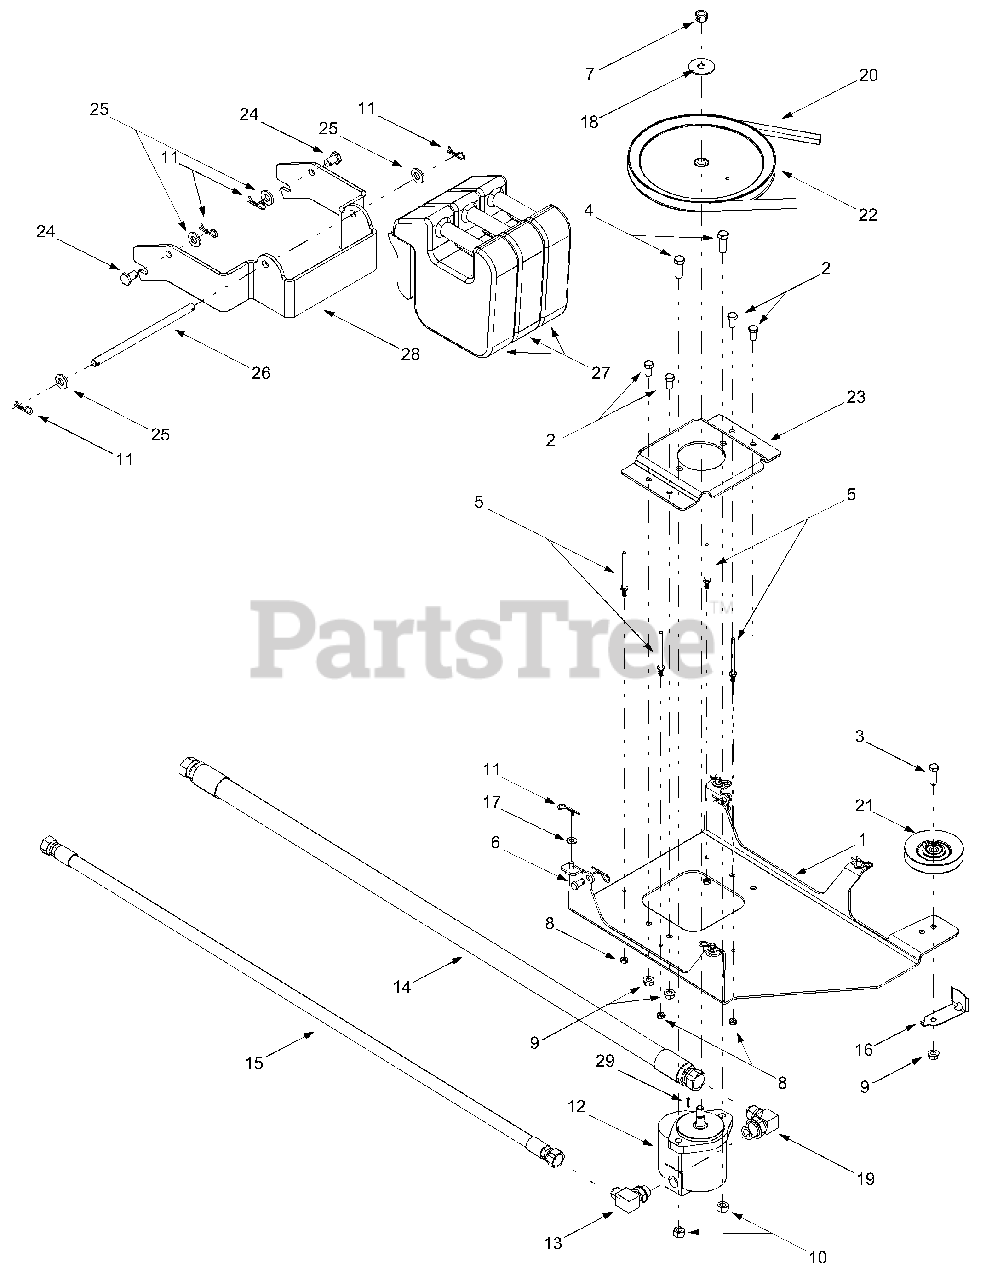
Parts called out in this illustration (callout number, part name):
3	Hex Cap Screw, 3/8-16 x 1.25
4	Hex Cap Screw, 7/16-20
5	Belt Keeper Pin
6	Clevis Pin, 3/8 x .75
7	Hex Lock Nut, 1/2-20
8	Hex Lock Nut, 1/4-20
9	Hex Lock Nut, 3/8-16
10	Hex Lock Nut, 7/16-20
11	Click Pin, .092 x 1.64
12	Eaton Hydraulic Pump (Includes Ref. 29)
13	90 degree Hydraulic Adapter, 7/8
14	Hydraulic Hose, 1.0625-12 x 54
15	Hydraulic Hose, .875-14 x 49
16	Belt Guard
17	Flat Washer, .344 x .688
18	Flat Washer, .531 x 1.75
19	90 degree Hydraulic Adapter
20	V-belt
21	Idler Pulley, 5/8 x 4.0
22	Drive Pulley, 10.0
25	Flat Washer, .531 x 1.062
26	Weight Guard Rod
27	45 lb. Suitcase Weight
